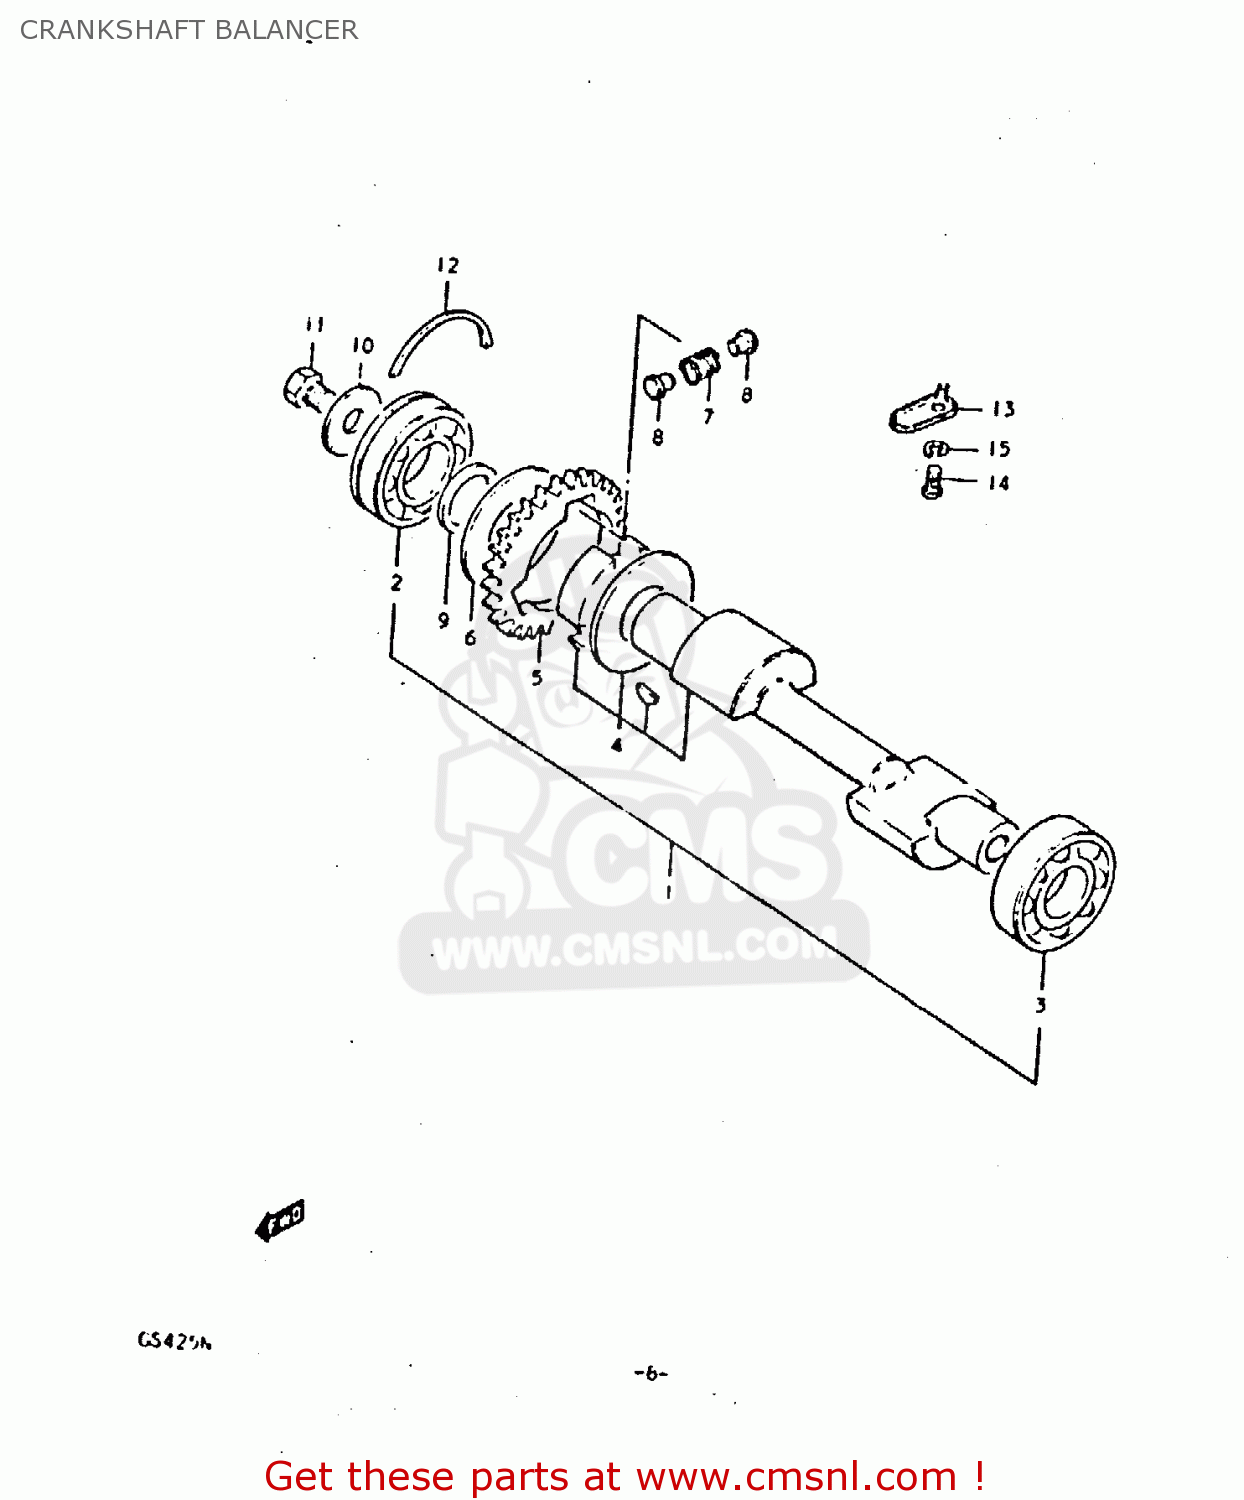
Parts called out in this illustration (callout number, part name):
1	BALANCER,CRANKSHAFT
2	BEARING
3	BEARING
4	CLUTCH SET,STARTER
5	GEAR,CRANK BALANCER DRIVE
6	WASHER (31X70X3)
7	SPRING
8	PIN
9	WASHER
10	WASHER
11	BOLT ,12X16
12	C RING
13	PLATE, OIL RESERVE
14	SCREW
15	LOCK WASHER
